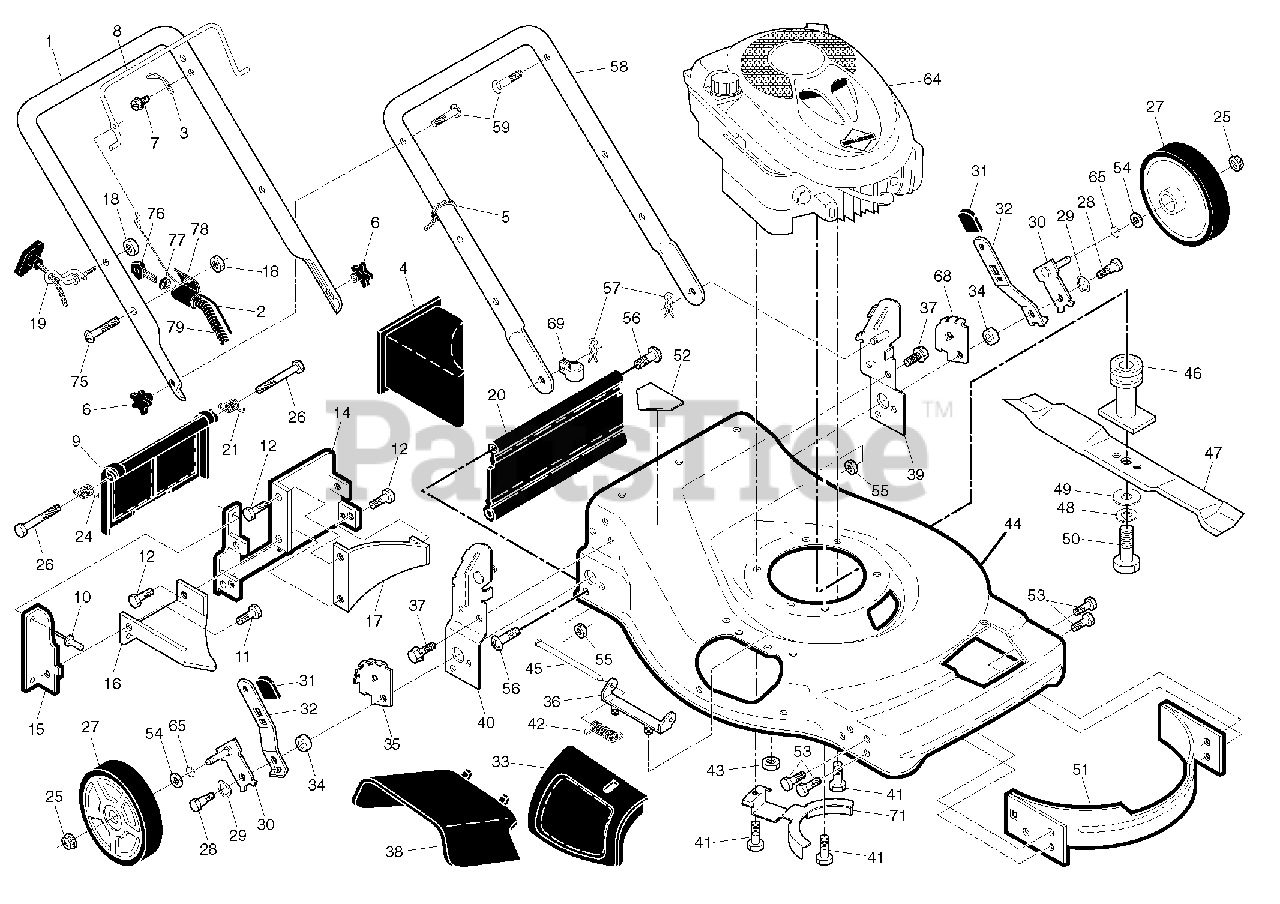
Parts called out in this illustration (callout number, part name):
1	Upper Handle
2	Cable, Operator Presence
3	Bracket, Upstop
4	Mulcher Plug
5	Wire Tie
6	Handle Knob
7	Screw
8	Control Bar
9	Rear Door Assembly
10	Pop Rivet
11	Screw, Self-Tapping #10-24 x 5/8
12	Screw, Hex Hex Head, Sems 1/4-20 x 1/2
14	Back Plate
15	Side Baffle
16	Discharge Baffle
17	Rear Baffle
18	Keps Locknut 1/4-20
19	Rope Guide
20	Rear Skirt
21	Spring, Rear Door, LH
24	Spring, Rear Door, RH
25	Nut, Hex, Flanged
26	Bolt, Rear Door
27	Wheel & Tire Assembly, Rear
28	Bolt, Shoulder 3/8-16 x 1
29	Washer, Curved, Cylindrical
30	Axle Arm Assembly
31	Selector Knob
32	Selector Spring
33	Mulcher Door
34	Spacer
35	Wheel Adjusting Bracket, RH
36	Hinge Bracket Assembly
37	Screw
38	Discharge Deflector
39	Handle Bracket Assembly, LH
40	Handle Bracket Assembly, RH
41	Screw, Hex Head, Threaded, Rolled 3/8-16 x 1-1/8
42	Spring, Torsion
43	Nut, Hex, Nylock
44	Kit, Mower Housing
45	Rod, Hinge
46	Blade Adapter / Pulley
47	Blade, 22"
48	Washer, Helical
49	Washer, Hardened
50	Screw, Machine, Hex Head 3/8-24 x 1-3/8 Grade 8
51	Kit, Front Baffle
52	Danger Decal
53	Screw, Serrated, TT 1/4-20
54	Washer, Flat
55	Locknut, Hex 3/8-16
56	Hinge Screw 1/4-20 x 1-1/4
57	Hairpin Cotter
58	Lower Handle
59	Handle Bolt
65	O-Ring
68	Wheel Adjusting Bracket, LH
69	Clip, Cable
71	Belt Keeper
75	Screw
76	Key
77	Nut, Cap
78	Key Start Switch
79	Wiring Harness
79	Operator's Manual, English
79	Operator's Manual, French
79	Repair Parts Manual
